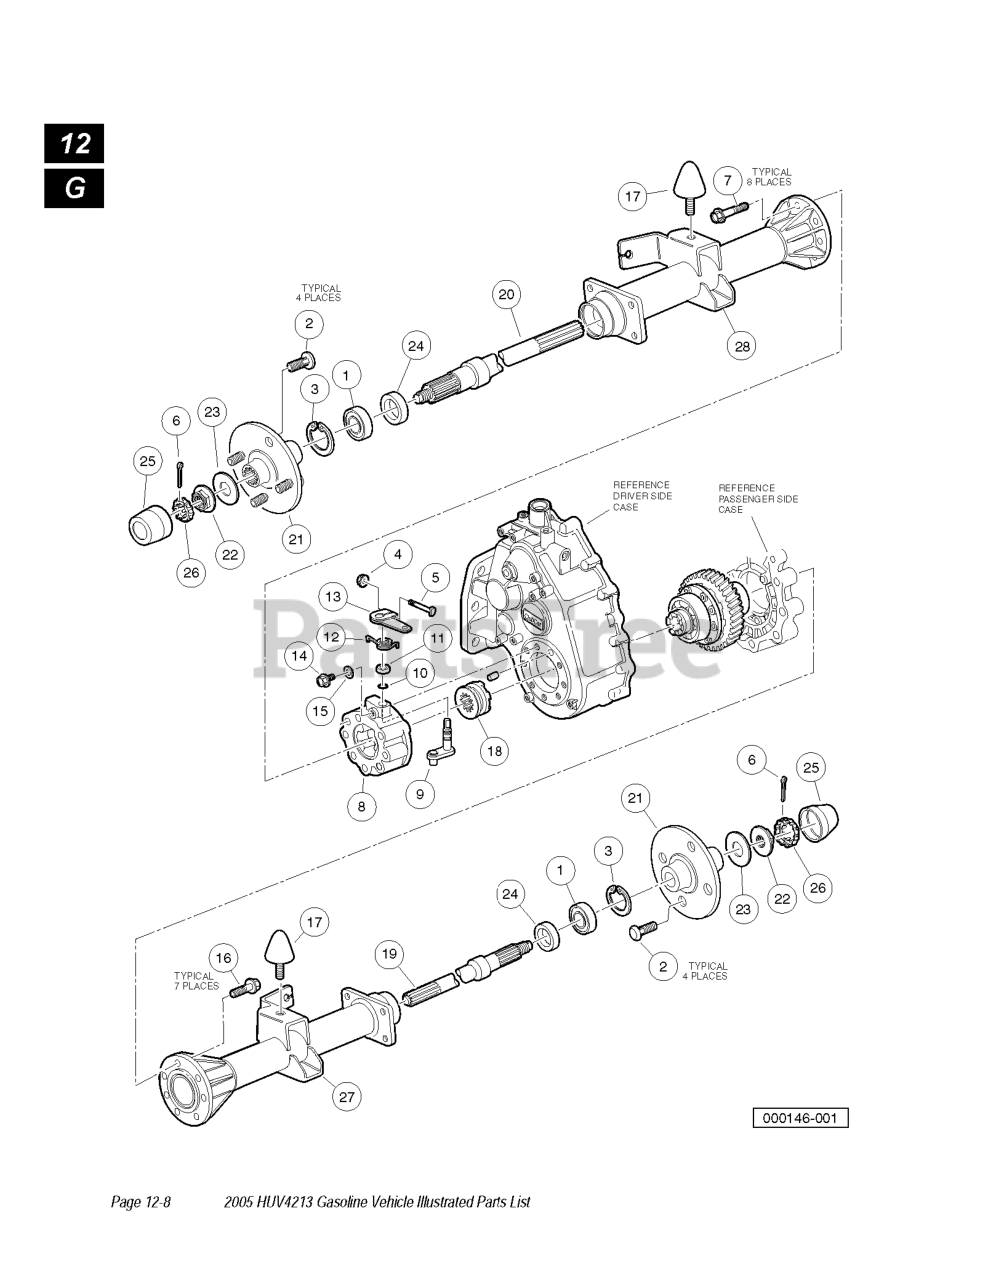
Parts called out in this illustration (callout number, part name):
1	OUTER AXLE, TUBE BEARING
3	CIRCLIP TYPE C
5	BOLT, M6 SPECIAL
6	PIN-COTTER - .312 X 1.25"
7	BOLT, M10 X 1.5 X 70MM
8	HOUSING, DIFFERENTAL LOCK
9	LEVER, DIFFERENTAL LOCK
10	O-RING DIFFERENTAL LOCK
11	SPACER, DIFFERENTAL LOCK
12	SPRING, DIFFERENTAL LOCK
13	ARM LEVER, DIFFERENTAL LOCK
14	SCREW, M6 X 1 X 10MM
16	BOLT, M10 X 1.5 X 30MM
17	STUD MOUNT
18	SHIFTER, 15T
19	AXLE SHAFT - RH
20	AXLE SHAFT - LH
21	WHEEL BOLT FLANGE
22	NUT - AXLE FLANGE
23	WASHER - AXLE
25	CENTER CAP, RUBBER
26	LOCKING CAP, NUT
27	AXLE TUBE, HD, RH
28	AXLE TUBE, HD, LH
